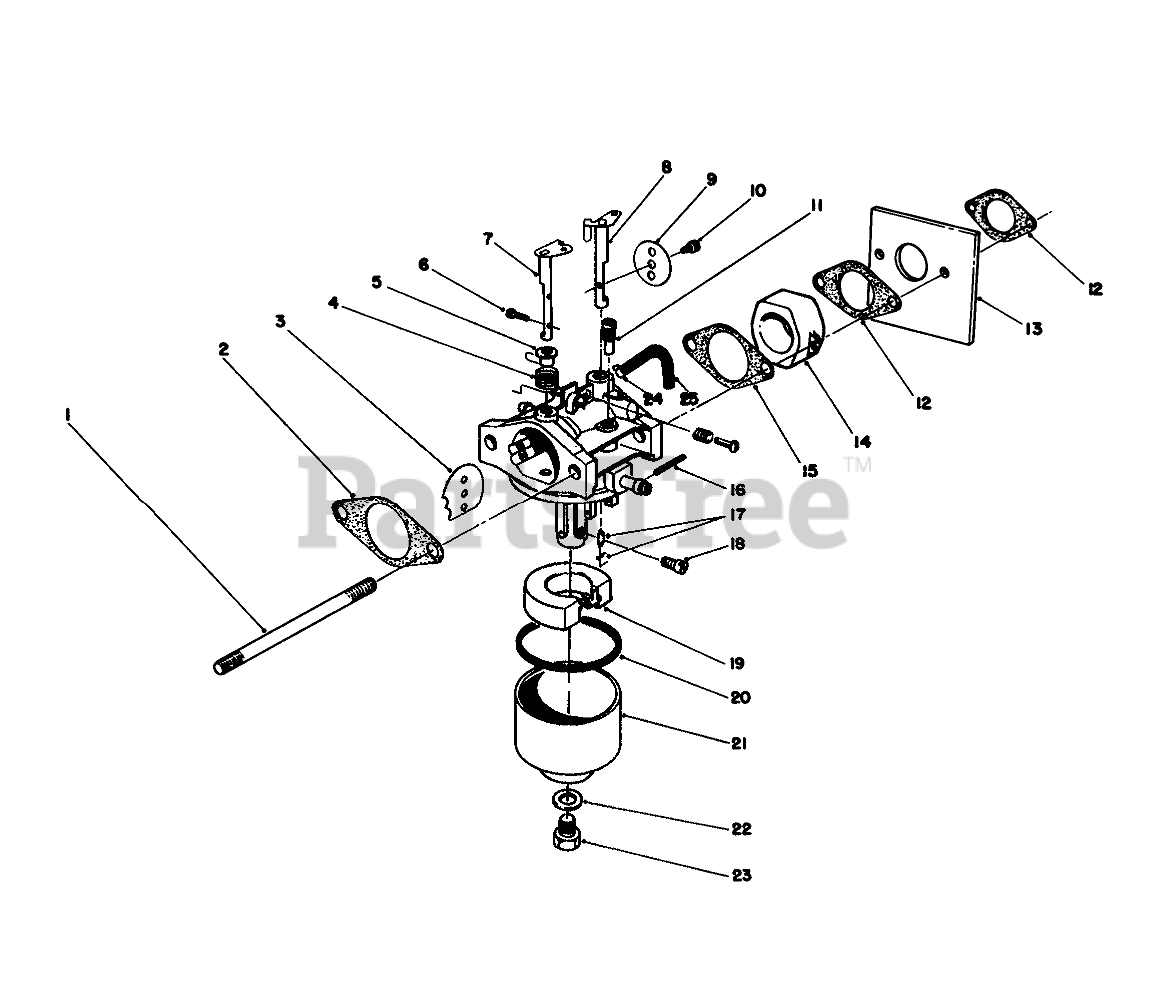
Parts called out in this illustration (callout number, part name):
1	STUD-CARBURETOR
2	GASKET-AIR CLEANER
3	PLATE
4	SPRING
5	BUSHING
6	SCREW
7	SHAFT-CHOKE
8	SHAFT
9	PLATE
10	Screw-Throttle
11	PILOT JET
12	GASKET
13	SHIELD-CARBURETOR
14	INSULATOR-CARBURETOR
15	GASKET-CARB
16	Pin
17	NEEDLE
18	JET-MAIN
19	FLOAT
20	GASKET
21	Bowl-Float
22	GASKET
23	Bolt
24	CLAMP
25	VENT TUBE
